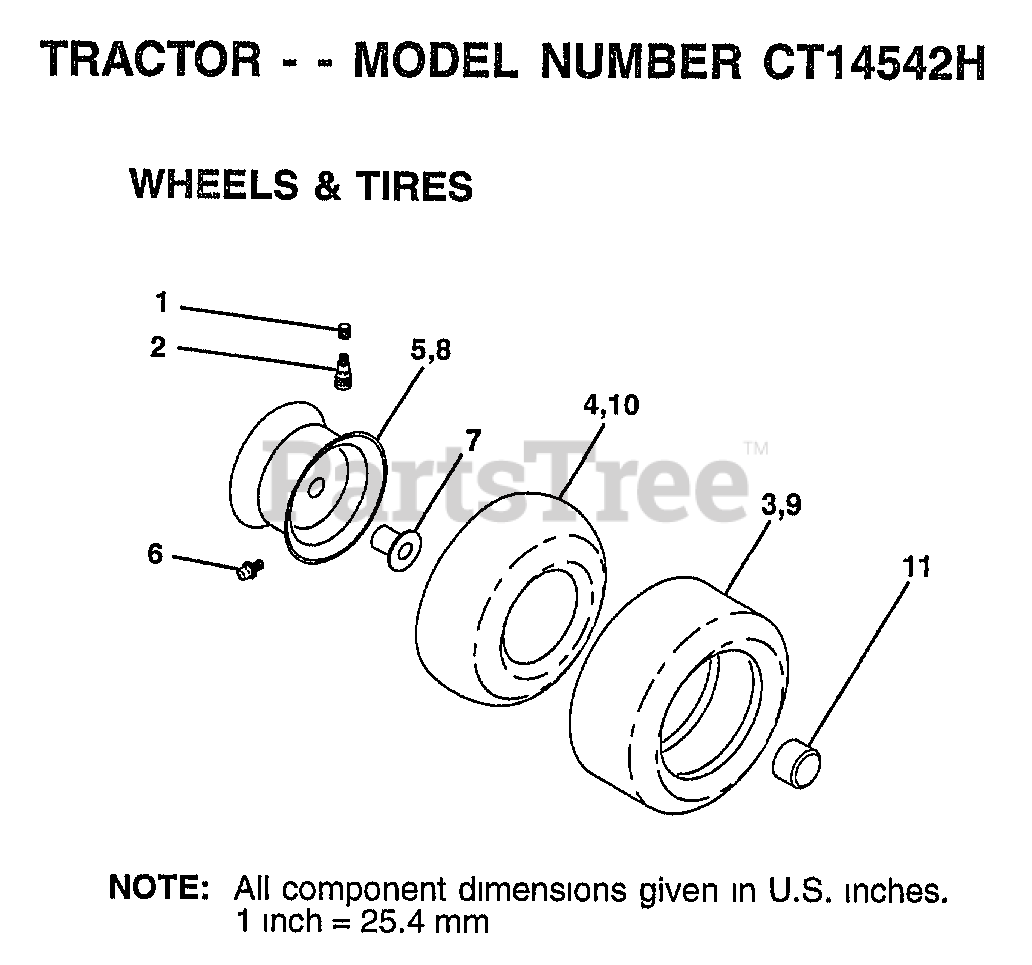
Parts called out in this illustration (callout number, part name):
1	VALVE CAP
2	VALVE STEM LT
4	TUBE.5.3/4.5/6
5	RIM.FRONT.6.YELLO
6	FITTING LT
7	"FLANGE, BEARING"
10	TUBE.18X9.5-8
11	HUB CAP
